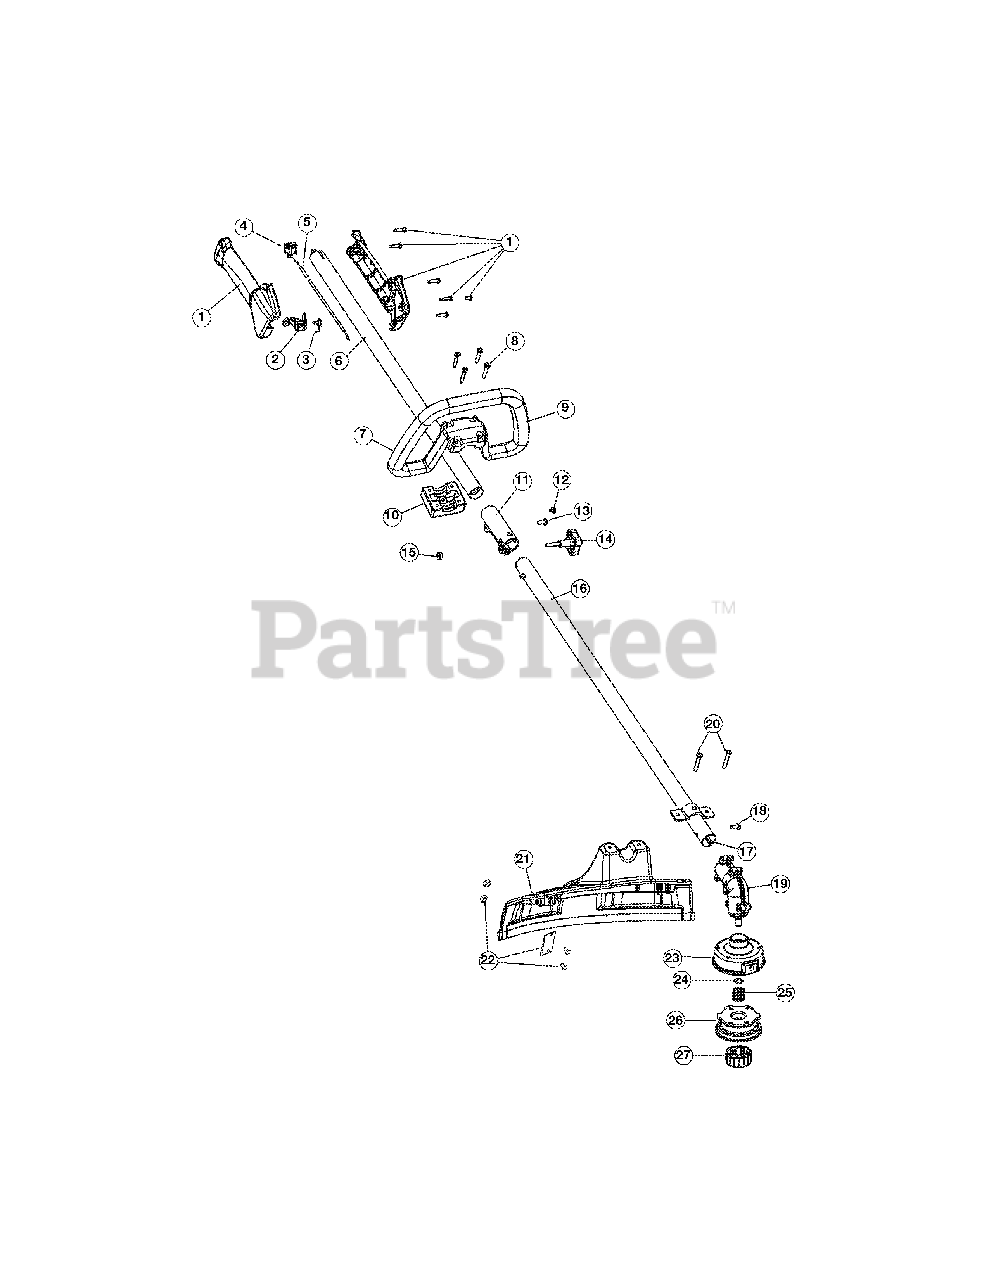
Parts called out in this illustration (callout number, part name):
1	Throttle Housing Assembly (Incl. 2-4)
2	Throttle Trigger
3	Throttle Trigger Spring
5	Throttle Cable Assembly
6	Upper Drive Shaft Housing Assembly
7	Deluxe D-Handle Assembly (Incl. 8-10)
9	D-Handle
10	Bottom Clamp
11	Split Boom Coupler (Incl. 12-15)
14	Adjustment Knob (Incl. 15)
15	Knob Retaining Nut
16	Lower Drive Shaft Housing Assembly
17	Lower Flexible Drive Shaft
18	Anti-Rotation Screw
19	Gear Box Assembly (Incl. 18 & 23-27)
20	Shield Mounting Screws
21	Shield Assembly (Incl. 22)
22	Blade Assembly
23	Outer Spool Assembly
24	Retainer
26	Inner Reel
27	Bump Knob Assembly
